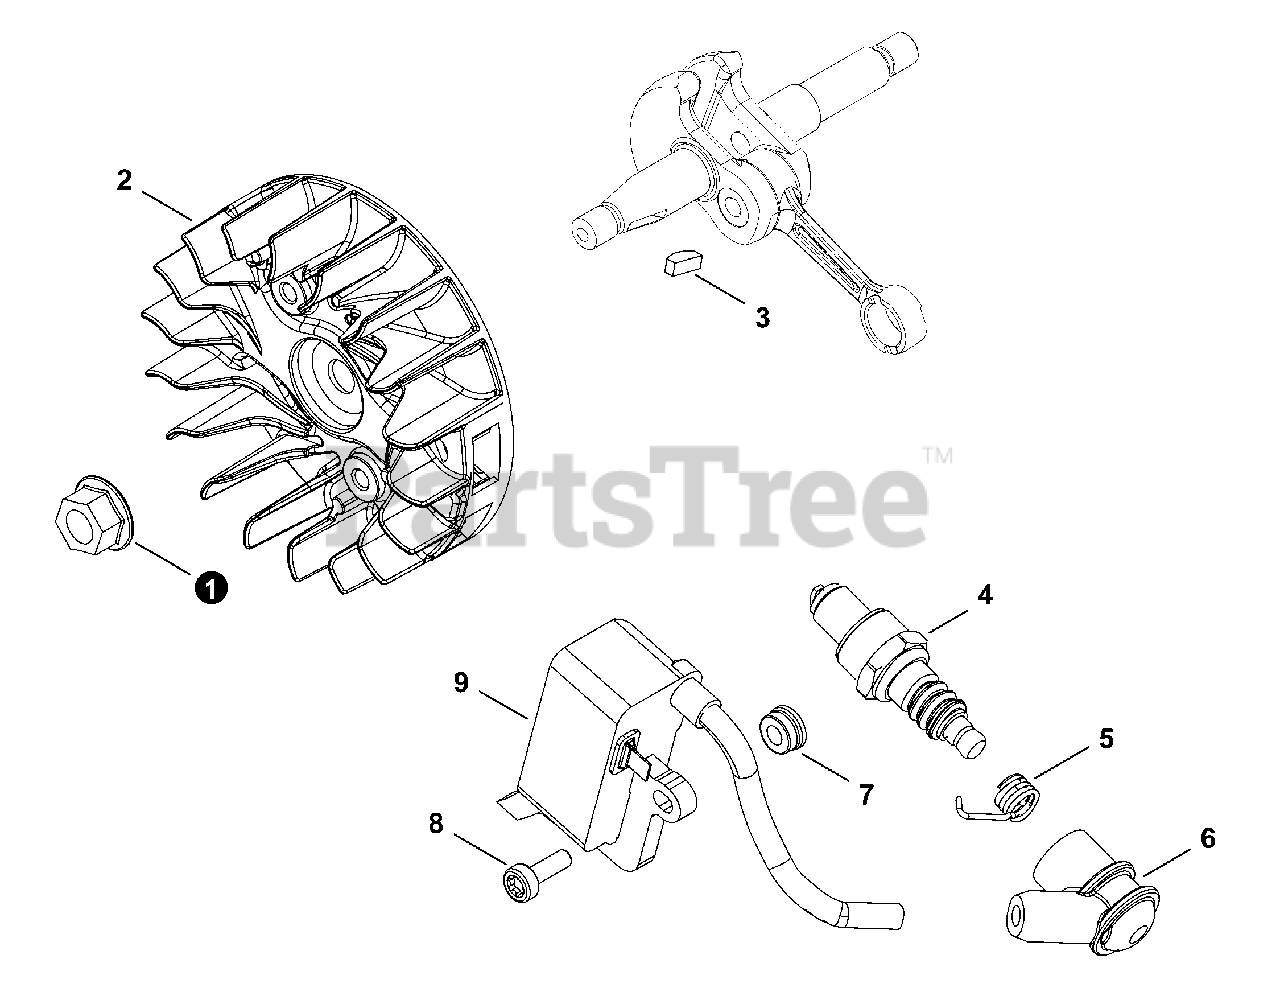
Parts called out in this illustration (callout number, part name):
2	FLYWHEEL
3	KEY, WOODRUFF
4	SPARK PLUG - CMR7H
5	TERMINAL, SPARK PLUG
6	CAP, SPARK PLUG
7	COLLAR 4
8	BOLT, TORX 4×16
9	COIL, IGNITION
